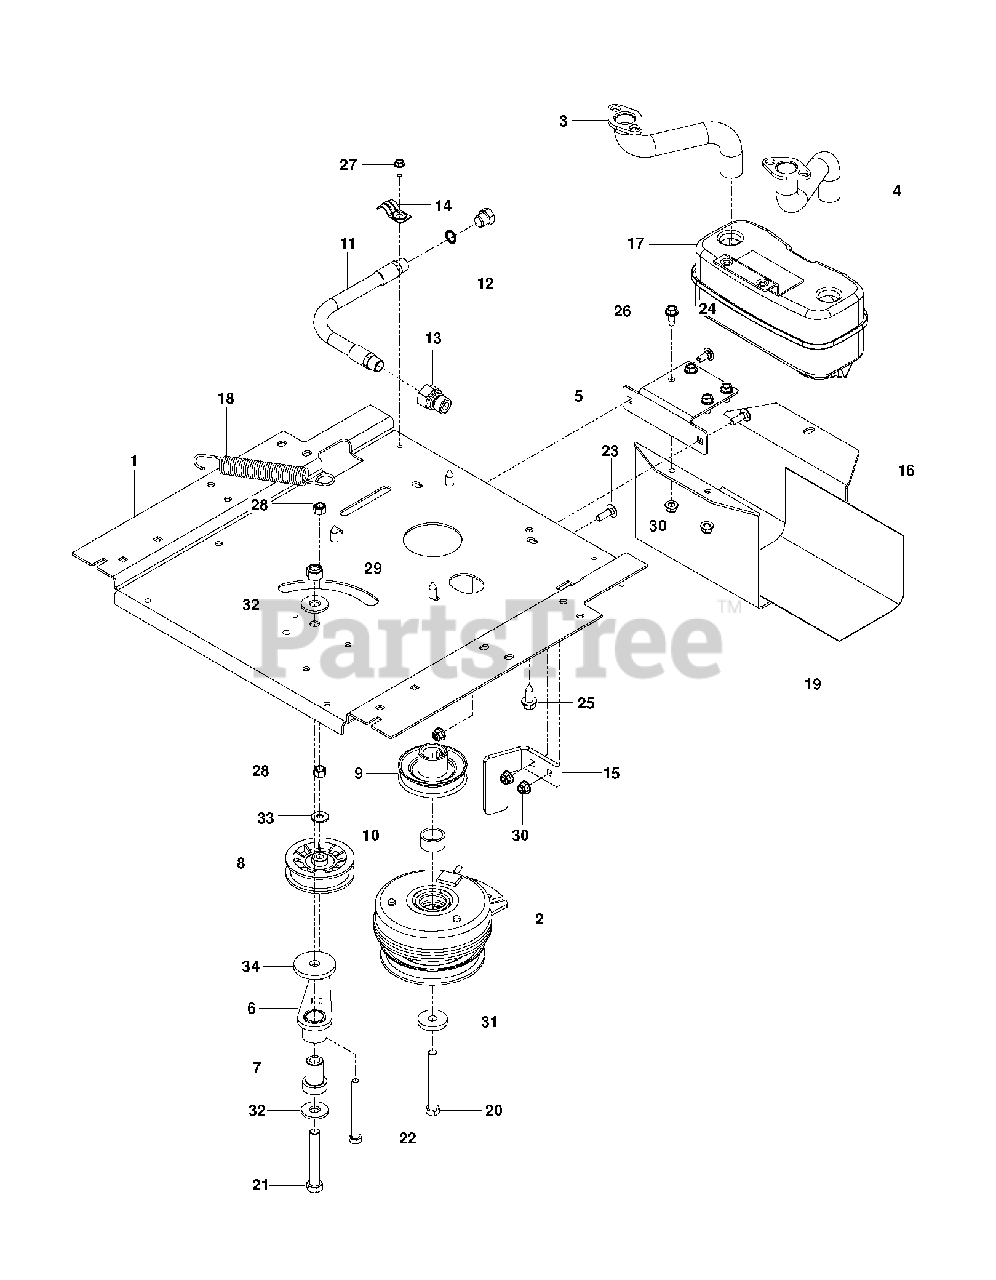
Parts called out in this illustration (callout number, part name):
1	PLATE.ENGINE.PNT.23".RZ.EDIP
2	CLUTCH.105.FT-LBS
3	TUBE.EXHAUST.RH.FR961/FR730
4	TUBE.EXHAUST.LH.FR961/FR730
5	BRACKET MUFFLER MS431BLK
6	ARM IDLER
7	IDLER SPINDLE
8	PULLEY, IDLER RAKE & ZTR
9	RP PULLEY, ENGINE
10	T & B SPACER
11	HOSE.ASSEMBLY.OIL.DRAIN
12	PLUG OIL DRAIN
13	ADAPTER, OIL DRAIN
15	STOP, CLUTCH, BLACK
16	GUARD.MUFFLER.WO.TOW.HITCHX431
17	MUFFLER ASM TWIN
18	SPRING, DECK DRIVE
19	HEAT SHIELD
20	CLUTCH BOLT7/16-20X3.5 GR524HR
21	HCS 1/2-13 X 3-1/4 GD 5 ZD
22	HCS 3/8-16X3-1/2 TAPBLT GR5 ZD
24	BOLT 5/16-18 X3/4 ZN/YEL GR 5
25	SCREW 3/8-16X1
26	SCREW
27	SCR 1/4-20X5/8 HEX SELF TAP ZD
28	NUT 3/8-16 NYLOC
29	NUT.LK.W/WSH.1/2.
30	5/16-18 NYLOC FLANGE NUT
32	WASHER.9/16 X 1 3/8 X 12 GA.
33	WASHER
34	HEAVY WASHER
